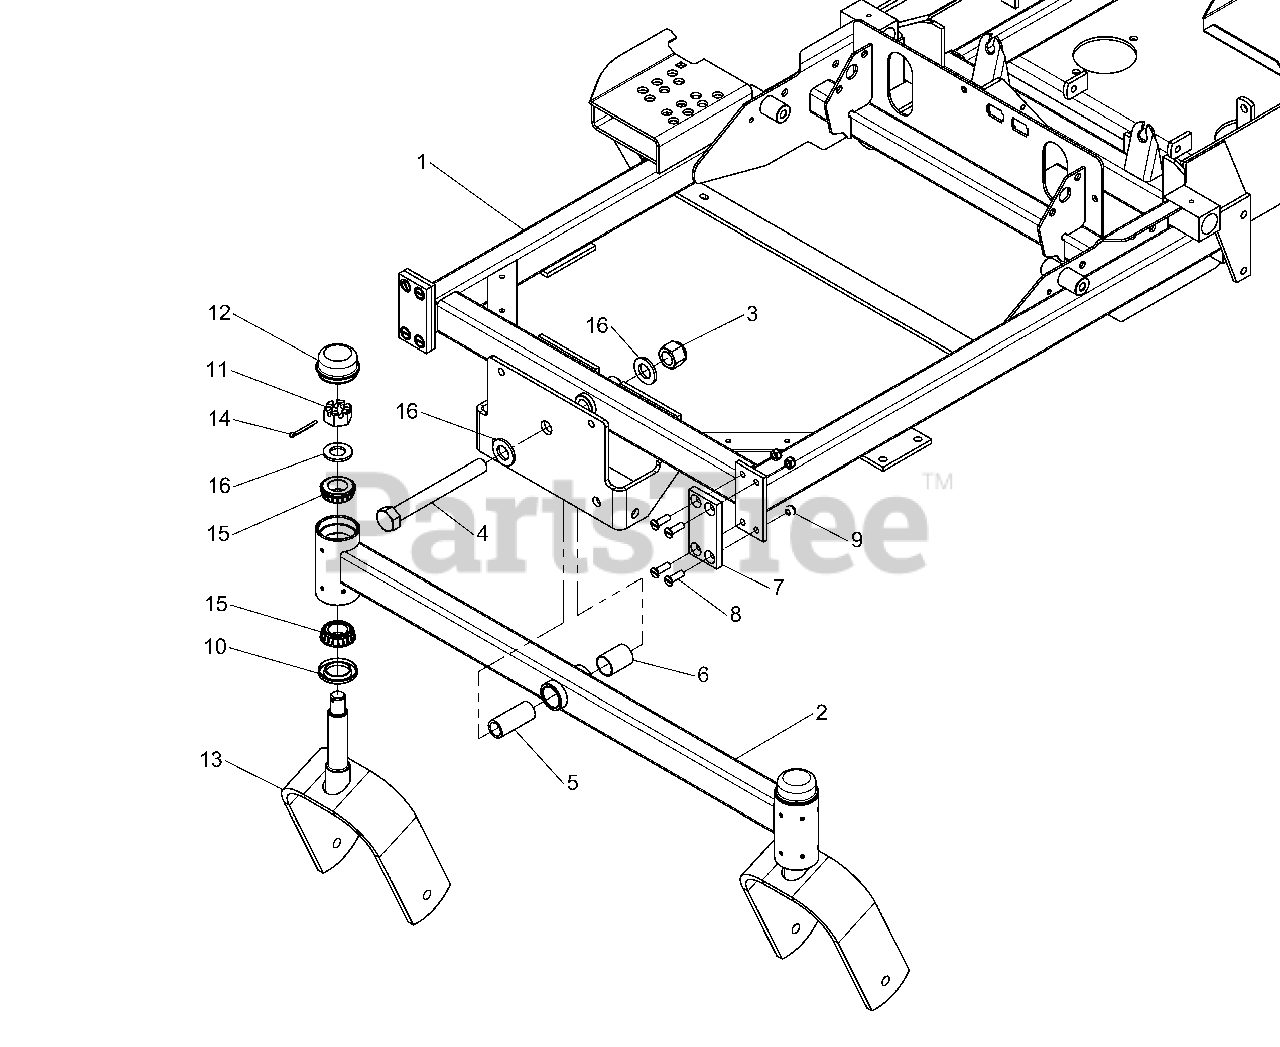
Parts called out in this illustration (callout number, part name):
1	MAIN FRAME ASSEMBLY (Early Models)
1	MAIN FRAME ASSEMBLY (Later Models with ROPS)
2	PIVOTING FRONT END ASSEMBLY
3	NUT, 3/4-16 Hex Nylon Lock
4	BOLT, 3/4-16 X 6-1/2"
5	SPACER, .75 X 1.00 X 2.38
6	PIVOT BEARING
7	FRICTION PLATE
8	SCREW, 5/16-18 X 1 PHILLIPS HD, BZ
9	NUT 5/16-18 Hex Nylon Lock
10	GREASE SEAL
11	NUT, 3/4-16 Hex Slotted
13	CASTER YOKE
14	COTTER PIN, 1/4" x 1-1/4"
15	BEARING, Tapered Roller
16	WASHER, 3/4" SAE
17	PIVOT BEARING
